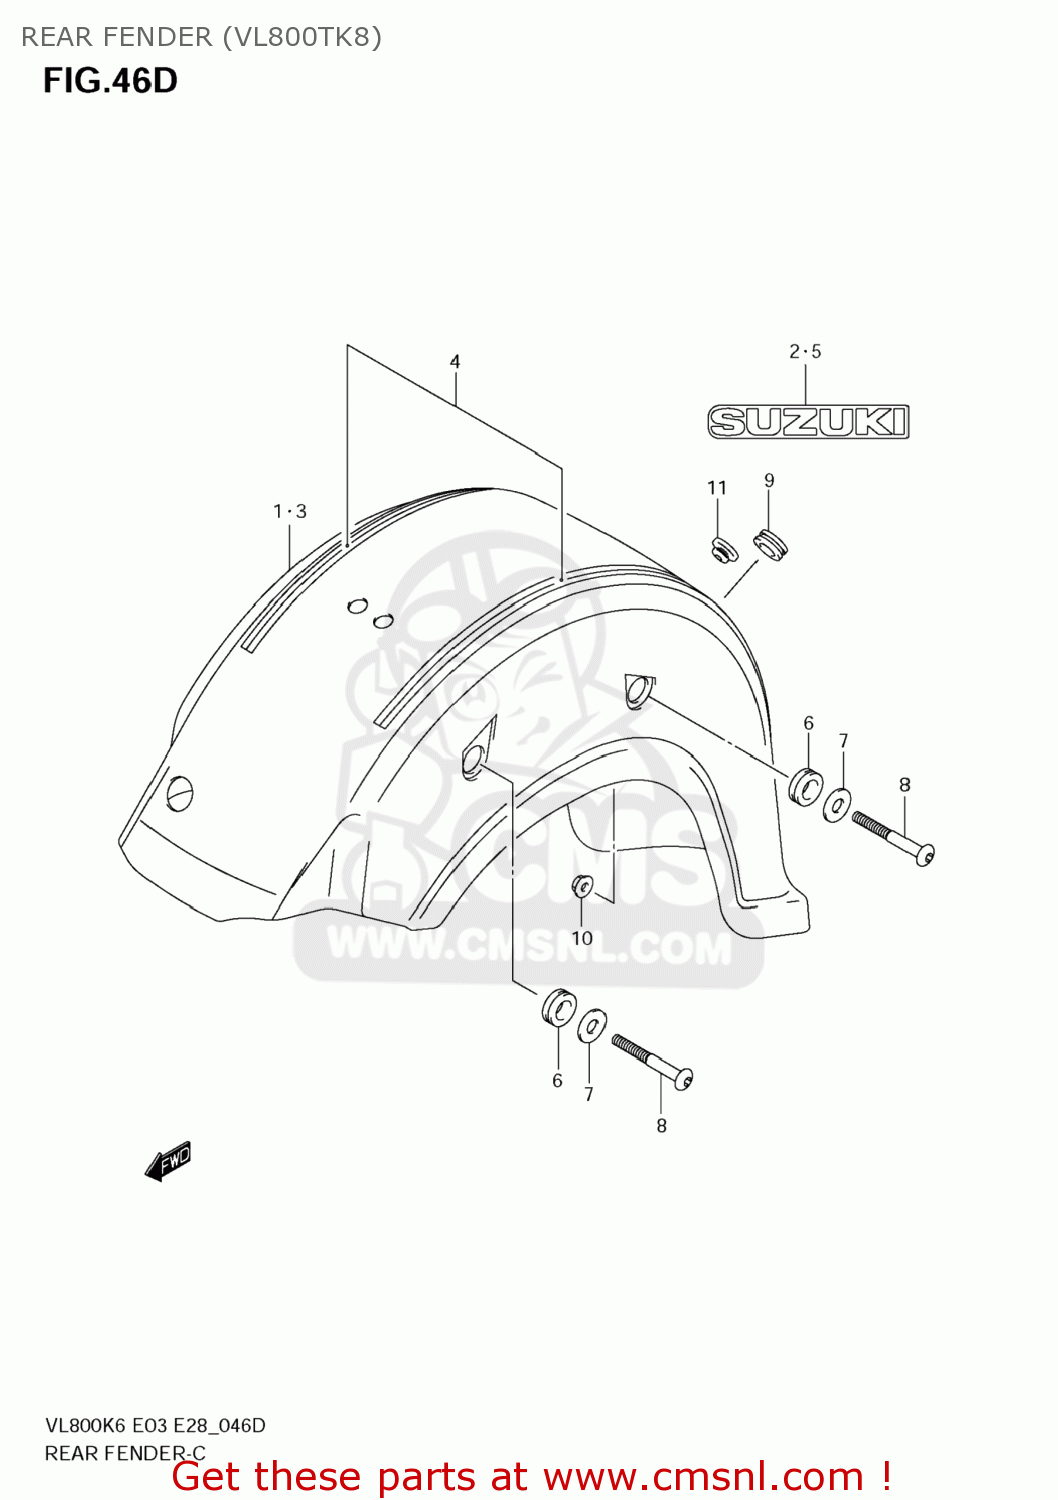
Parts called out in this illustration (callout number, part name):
1	FENDER,RR
2	EMBLEM,SUZUKI
3	FENDER,RR
4	TAPE SET,RR FENDER
5	EMBLEM,SUZUKI
6	CUSHION,FRAME COVER UPR RR
7	WASHER(15.5X26X2.3)
8	BOLT,RR FENDER
9	CUSHION
10	NUT
11	CUSHION
